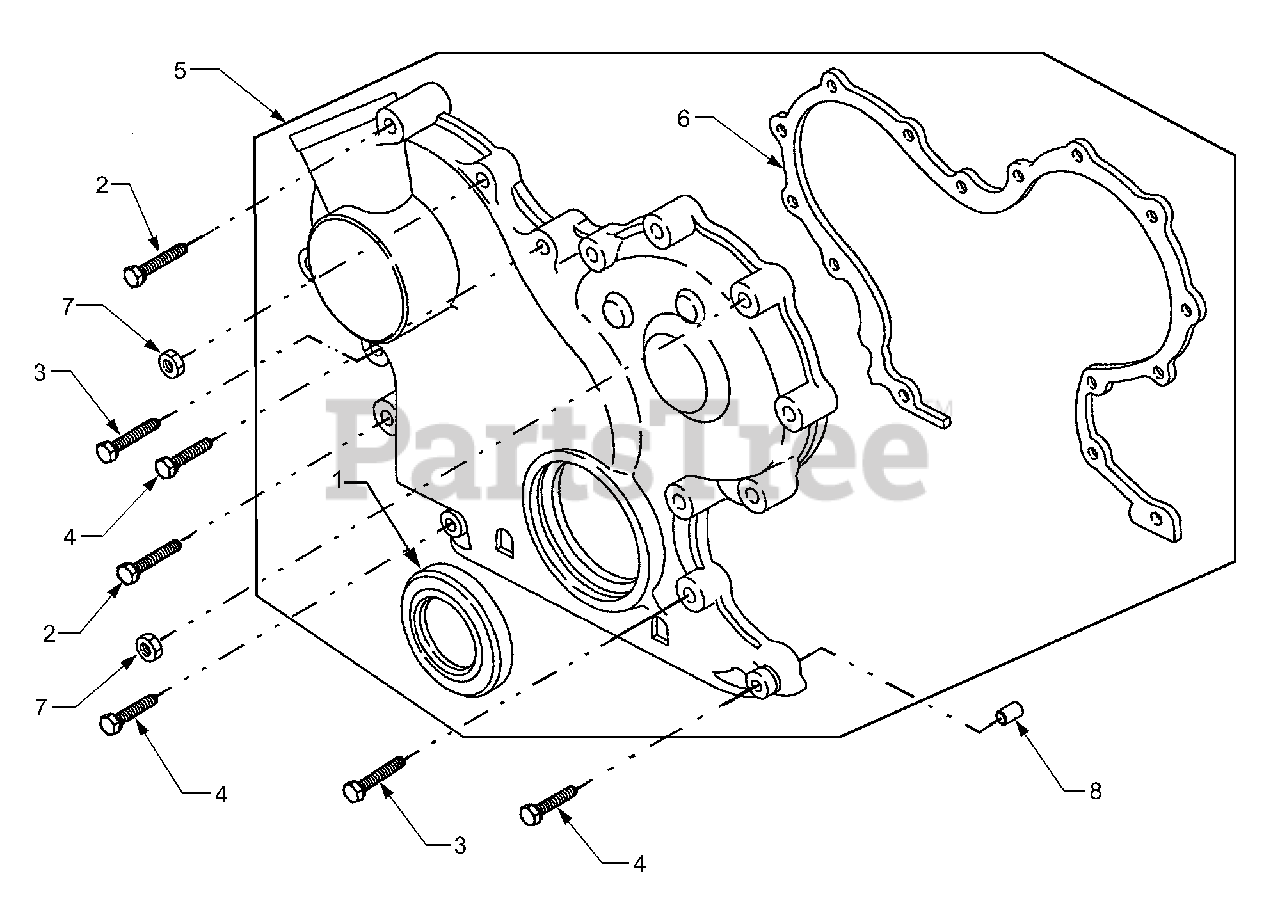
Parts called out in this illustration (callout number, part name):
1	Seal, Oil
2	Screw, Hex, 6mm
3	Screw, Hex, 6mm
4	Screw, Hex, 6mm
5	Cover Assembly, Gear
6	Gasket, Gear Cover
7	Nut, Hex Metric
8	Pin, Locating
